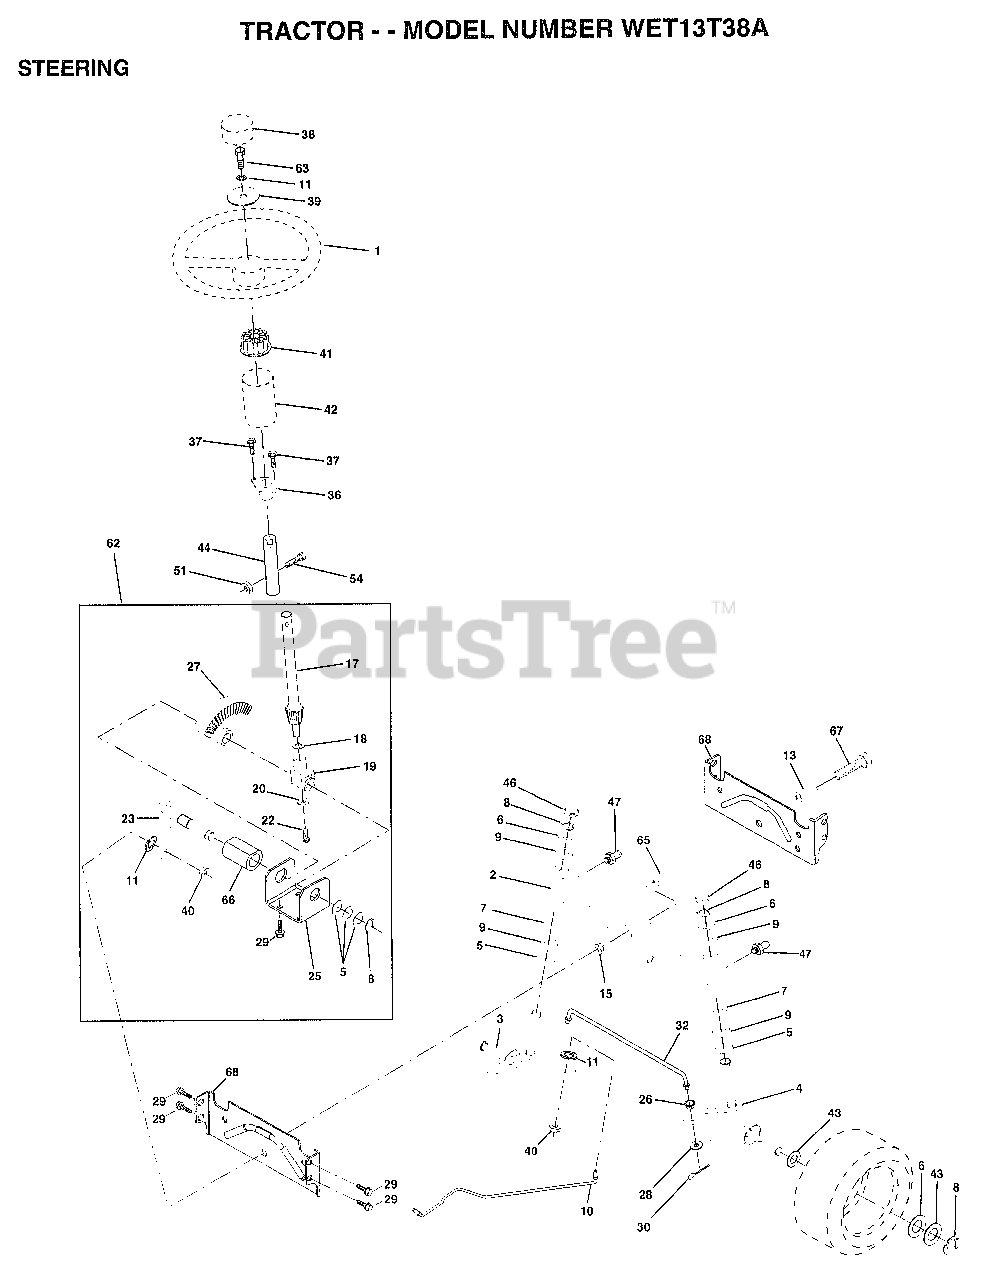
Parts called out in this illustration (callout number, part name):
1	WHEEL STR AYP BLK
2	AXLE ASM
3	SPINDLE.ASM.LH
4	"SPINDLE ASM,RH"
5	WASHER .T
6	WASHER
7	WASHER
8	RING
9	COL. SRTG. BEAR.
10	DRAGLINK-STAMPED
11	LOCKWASHER
13	BEARING AXLE
15	"NUT-LOC,FLANGE LT"
17	SHAFT ASM STEERIN
18	THRUST WASHER
19	SUPPORT.SHAFT
22	SCREW HEX SOC1/4-
25	BRKT-STEERING
26	BUSHING.DRAGLINK
27	GEAR SECTOR
28	WASHER
29	SCREW
30	COTTER PIN
32	TIE ROD
36	BUSHING.STEERING
37	"SCREW-TT,10-32 FL"
38	CAP STEER AYP
39	WASHER T
40	GRIPCO NUT
41	ADAPTER LT
42	BOOT.STEER.PL
44	EXT SHAFT STEERIN
46	CAP
47	ZERK M
51	NUT
54	BOLT
62	KIT STEERING ASM
63	BOLT
65	SPACER AXLE
66	"BEARING-ARM,PITMA"
67	BOLT
68	BRACE AXLE
